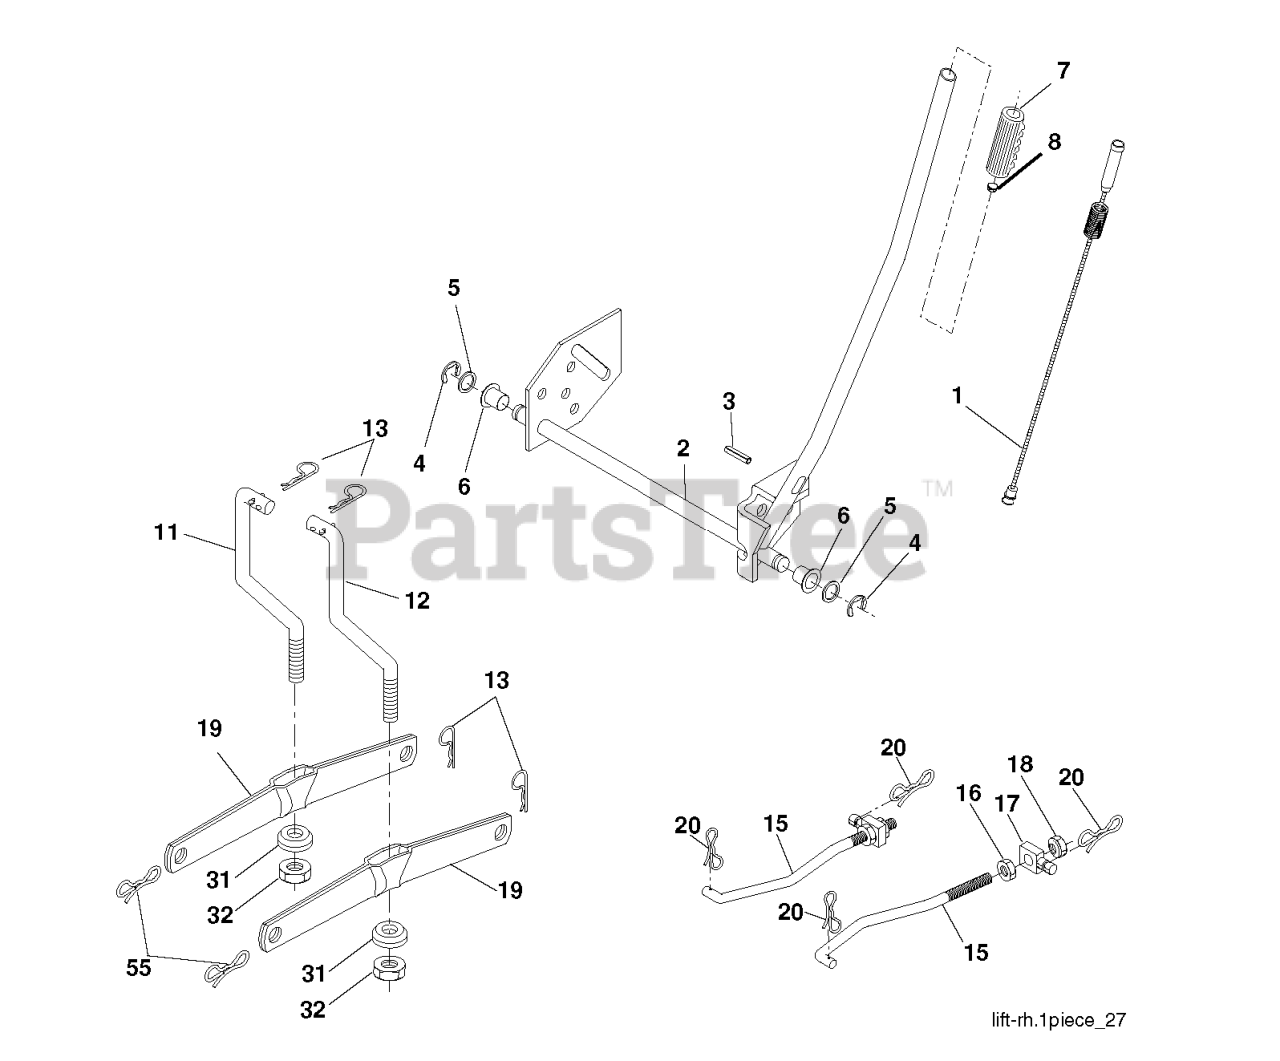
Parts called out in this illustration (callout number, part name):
1	PLUNGER.ASM.LIFT.LVR.BLK.17.32
2	SHAFT ASM R HANDLE
3	PIN GROOVE.
4	RETAINING RING LT
6	BEARING.NYLON
8	PLUNGER BUT KIT
11	LINK LIFT LH
12	LINK LIFT RH
13	RETAINER-SPRNG RB
15	LINK.SUSPENSION.FRONT
16	NUT.HEX.JAM.1/2-13
18	NUT.LK.W/WSH.1/2.
19	ARM.REAR.SUSPENSION
20	PIN.COTTER.7/16.BOW TI.
31	BEARING.PIVOT.LIFT
32	NUT CROWNLOCK 3/8-24
55	PIN.COTTER.5/16.BOW TI
